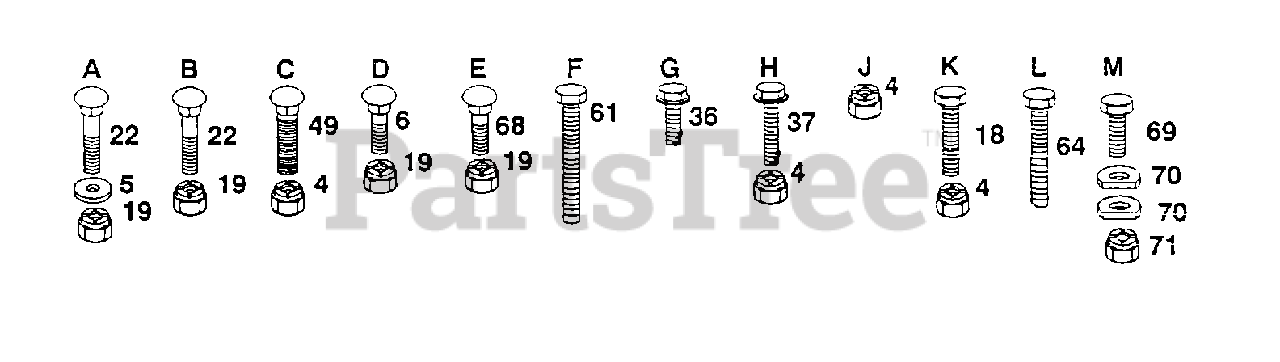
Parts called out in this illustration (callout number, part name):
5	WASHER M
6	BOLT
22	BOLT
36	SCREW
37	SCREW
49	BOLT
64	BOLT.3/8-14X1.25
69	BOLT LT
70	WASHER T
